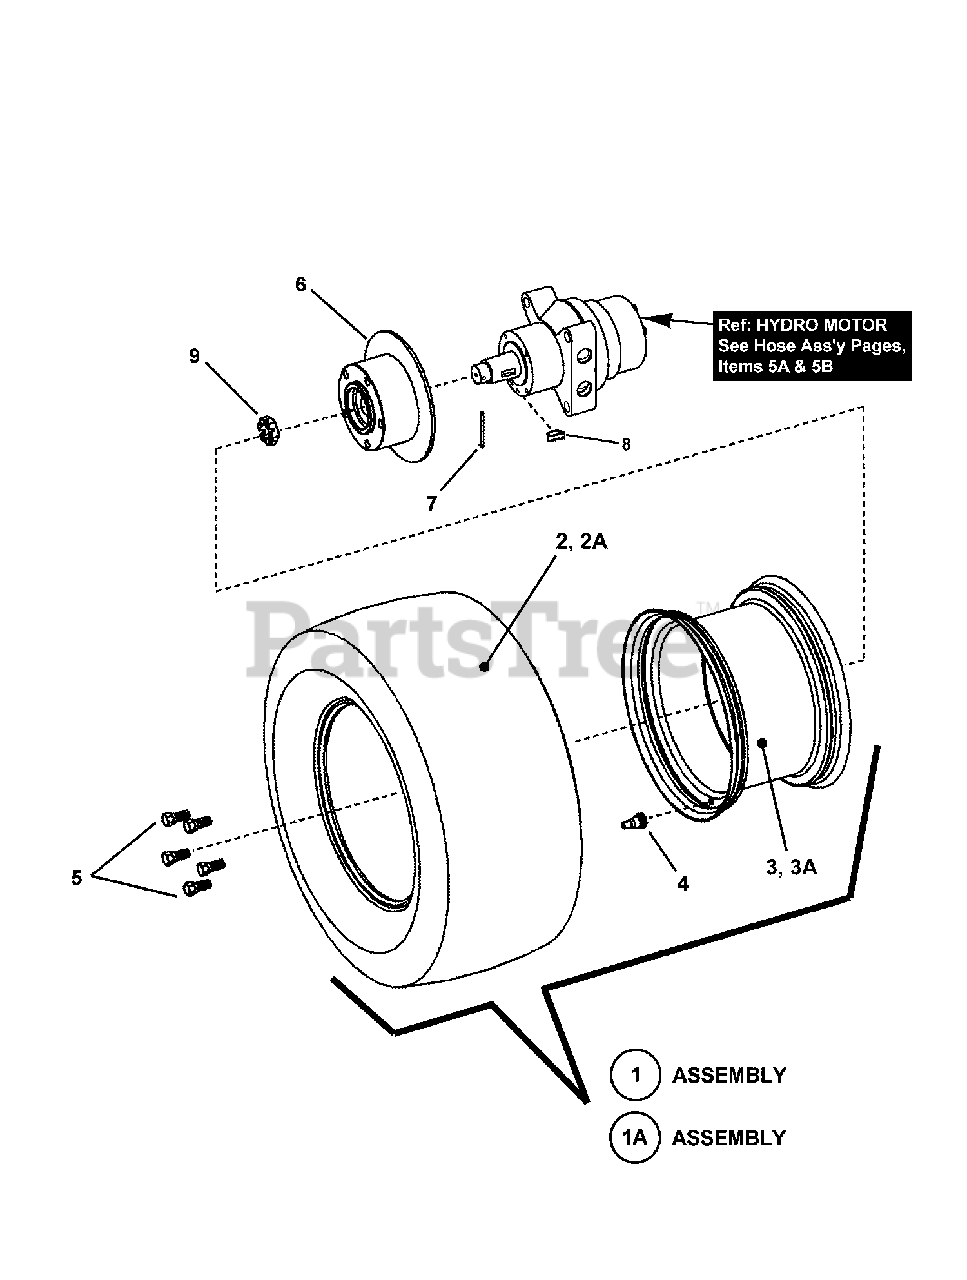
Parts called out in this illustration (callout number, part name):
1	ASSY, Wheel 23 x 10.50-12 (Incl. items 2, 3 & 4)
1A	ASSY, Wheel 24 x 12-12 (Incl. items 2A, 3A & 4)
2	TIRE, 23 x 10.50-12NHS 4Pr Turf Master TL
2A	TIRE, 24 x 12-12HHS 49R Turf Master
3	RIM, 12 x 7.00 5/4.5 AG Silver 237
3A	RIM, 12 x 8.50 5/4.5 RAW
4	AIR VALVE STEM & Cap
5	LUG BOLT, 1/2-20 UNF x 7/8"
6	DRUM, Brake (Ausco)
7	PIN, 9/64 x 1-1/2" Cotter
8	KEY, #11 Woodruff
9	NUT, 3/4-20 Slotted Hex
